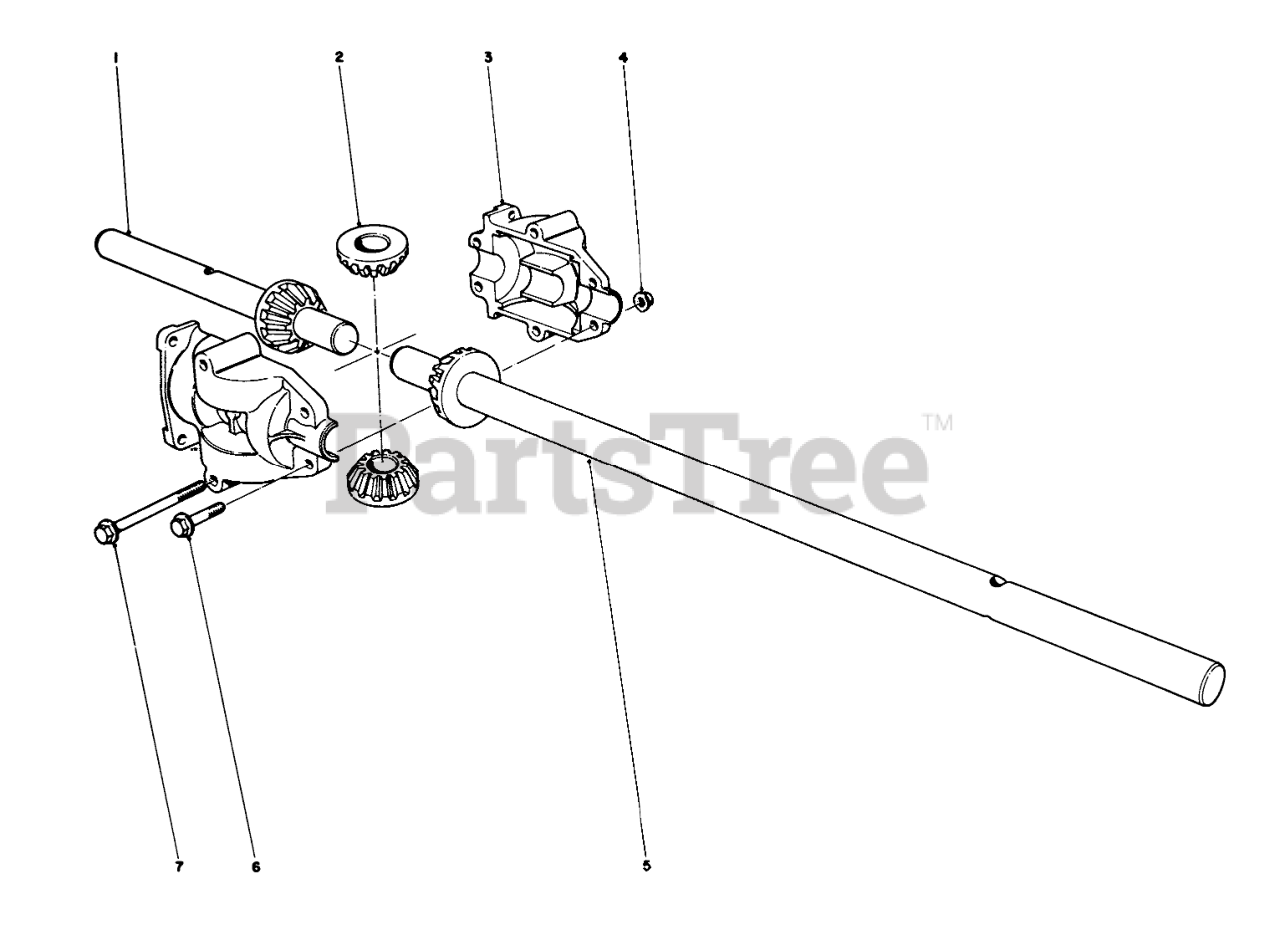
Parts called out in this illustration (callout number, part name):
1	Axle Shaft, Short
3	Housing Half
4	NUT-HHF
5	Axle Shaft, Long
